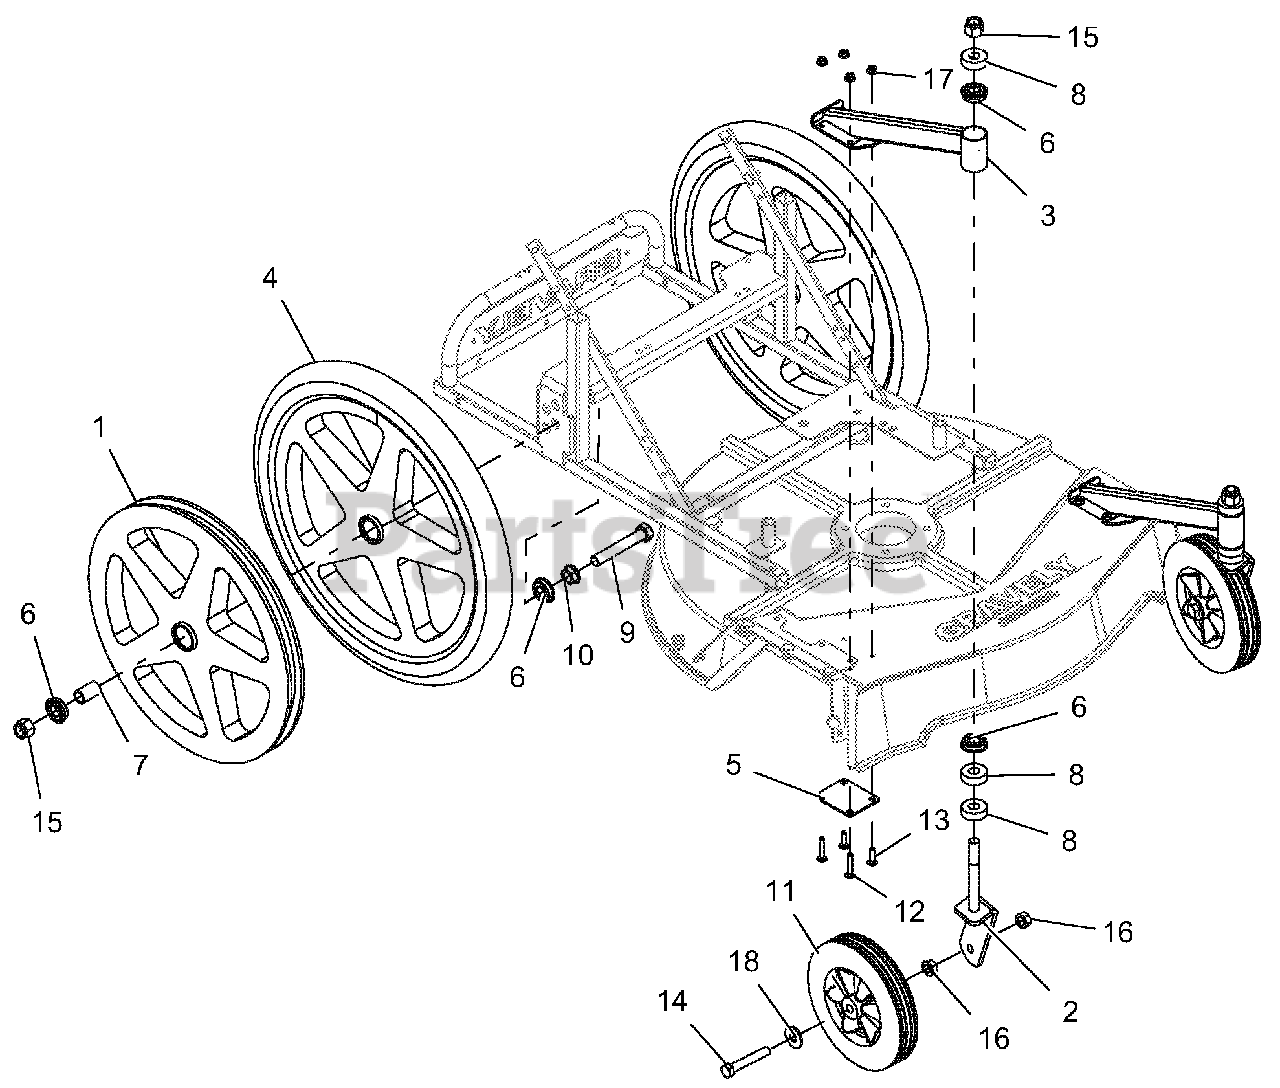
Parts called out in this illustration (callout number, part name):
1	WHEEL, 20" BLACK MAG
2	WLDMT, CASTER (RED)
3	WLDMT, CASTER SUPPORT, HWM 26" (RED)
4	WHEEL, 20" TIRE/RIM ASSY BLK/MAG
5	BACKER PLATE, CASTER SUPPORT (BLACK)
6	BALL BEARING 5/8 ID X 1-3/8OD
7	SPCR, .640X.840X1.39
8	SPCR, .65X1.50X.50 POLYPROPYL
9	BLT-HEX .62-11X4.00 GR5 FTH YZ
10	NUT-HEX FLANGE .62-11 GR5 YWZC
11	WHEEL, PLASTIC -8"X1.75" BLACK
12	BLT-RDHDSQNK .25-20X1.50 G5 Y
13	BLT-RDHDSQNK .25-20X1.00 G5 YWZC
14	BLT-HEX .50-13X3.00 GR5 YWZC
15	NUT-LK-NYL .625-11 YWZC
16	NUT, LK-TOP-FLG .50-13 YWZC
17	NUT, LK-TOP-FLG .25-20 YWZC
18	WSHR-FL-STL.563X1.38X.109YWZC
